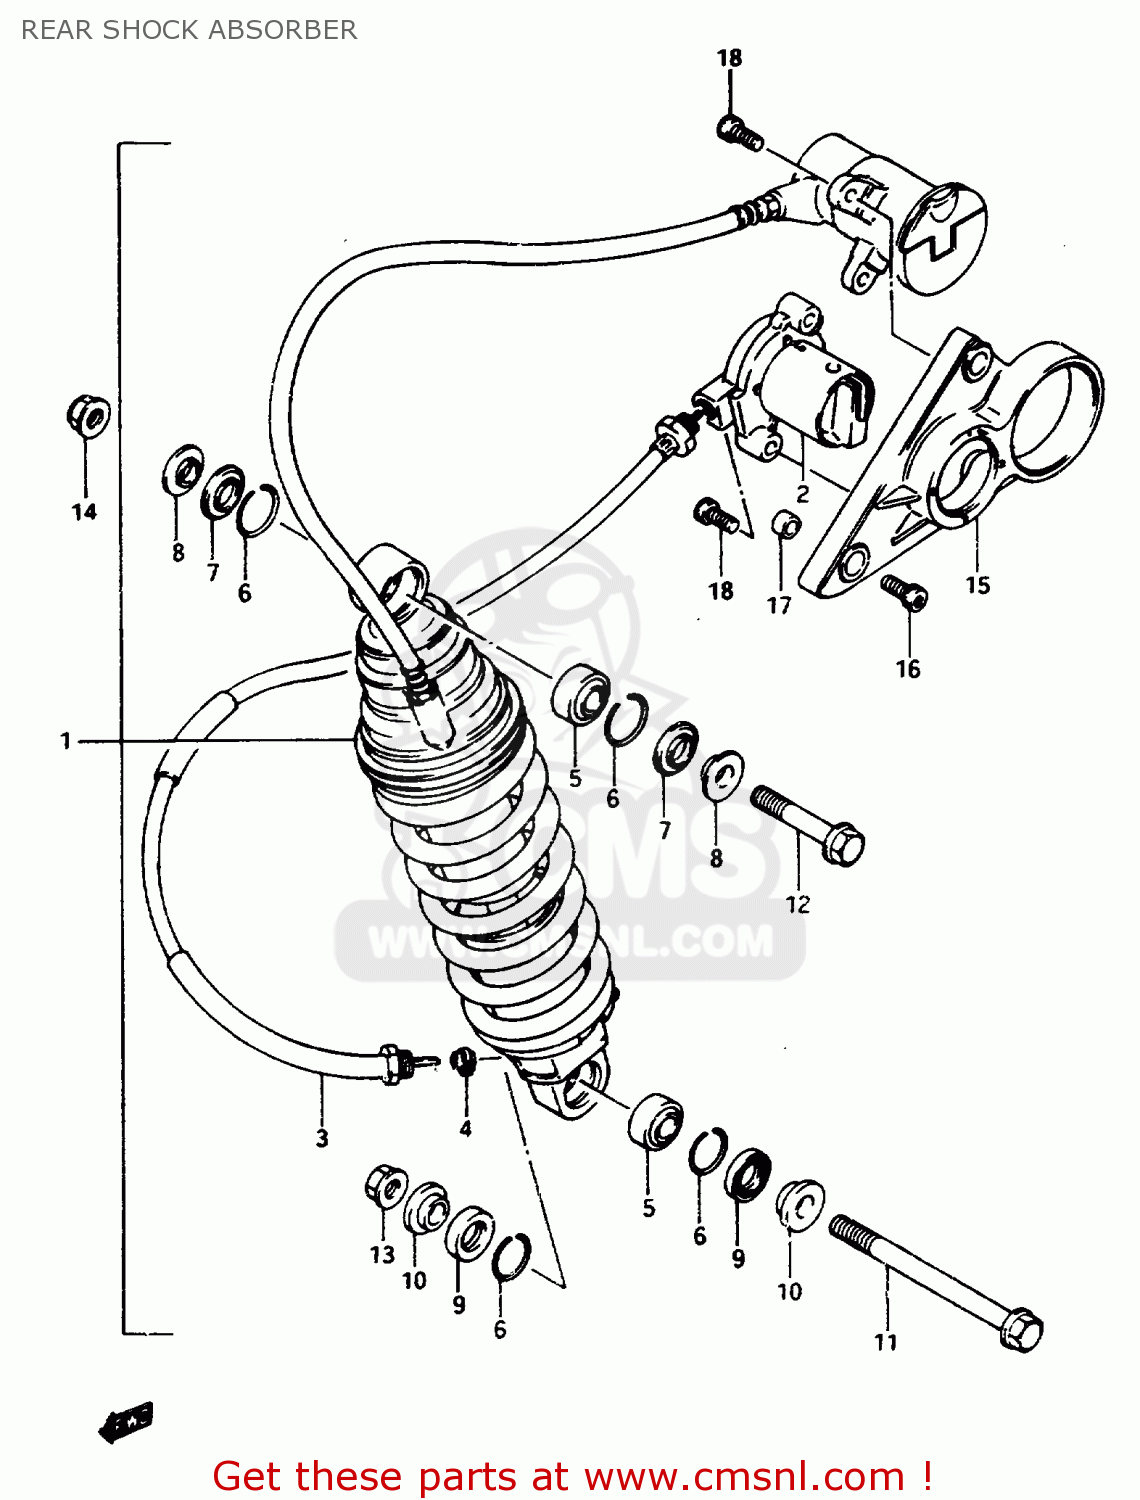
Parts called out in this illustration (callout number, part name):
1	SHOCK ABSORBER, REAR
2	ADJUSTER
3	CABLE,CONTROL
4	GEAR,DAMPER ADJUSTER
5	BEARING,REAR SHOCK ABSORBER
6	RING
7	SEAL,DUST UPR
8	COLLAR,UPR
9	SEAL,DUST
10	SPACER
11	BOLT(10X115)
12	BOLT(10X50)
13	NUT 10MM
14	NUT
15	BRACKET
16	BOLT
17	SPACER(6.5X12X6.9)
18	BOLT
